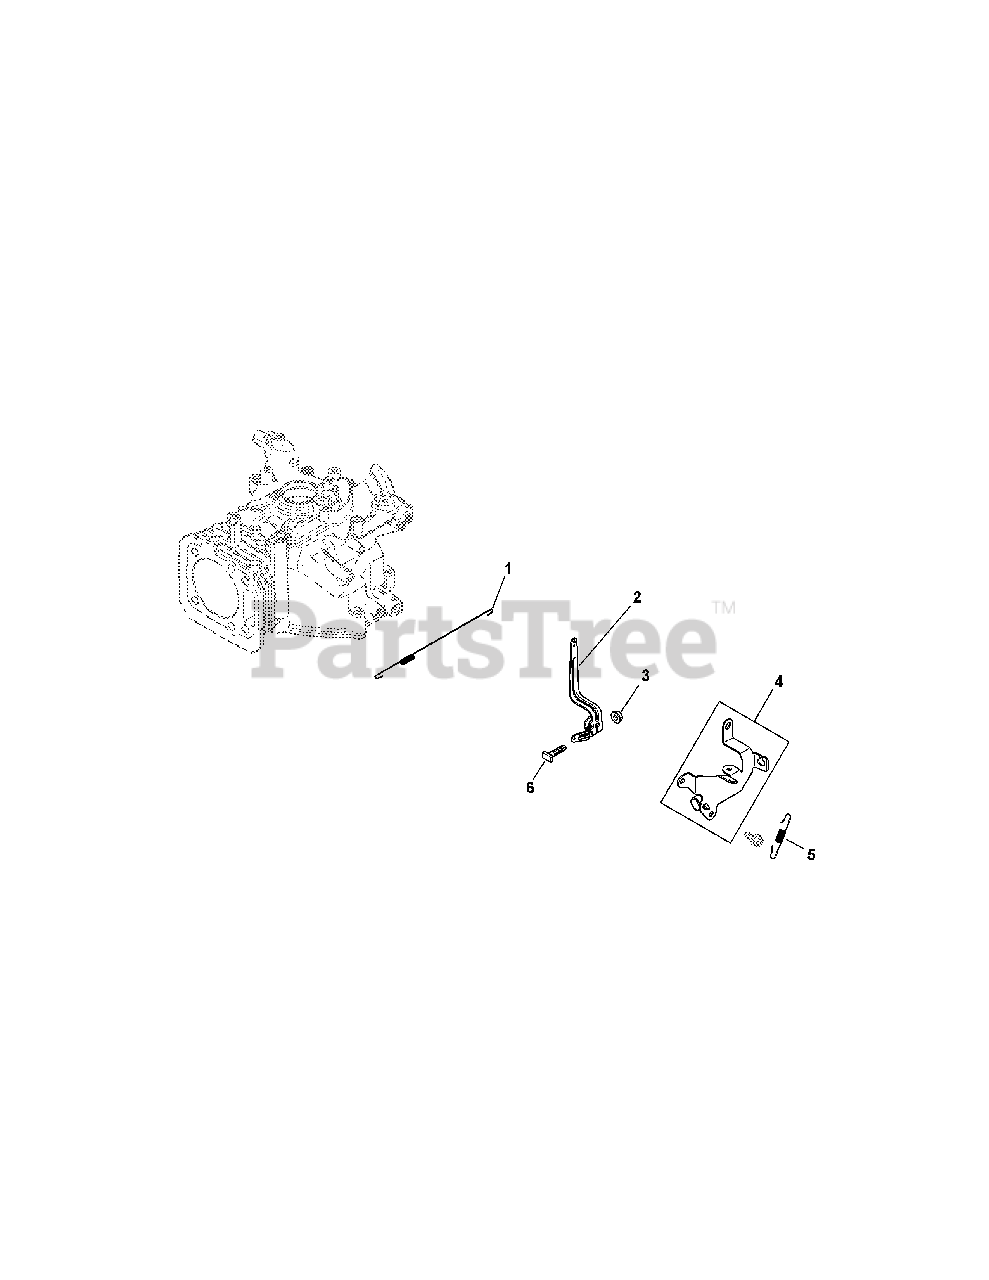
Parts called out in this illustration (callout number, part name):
1	Spring, Linkage
2	Lever, Governor
3	Nut, Flg M6X1.0
4	Control Assembly, Fixed Speed
5	Spring, Gov (2800-3300 Rpm)
6	Screw, Retangle Head (M6)
